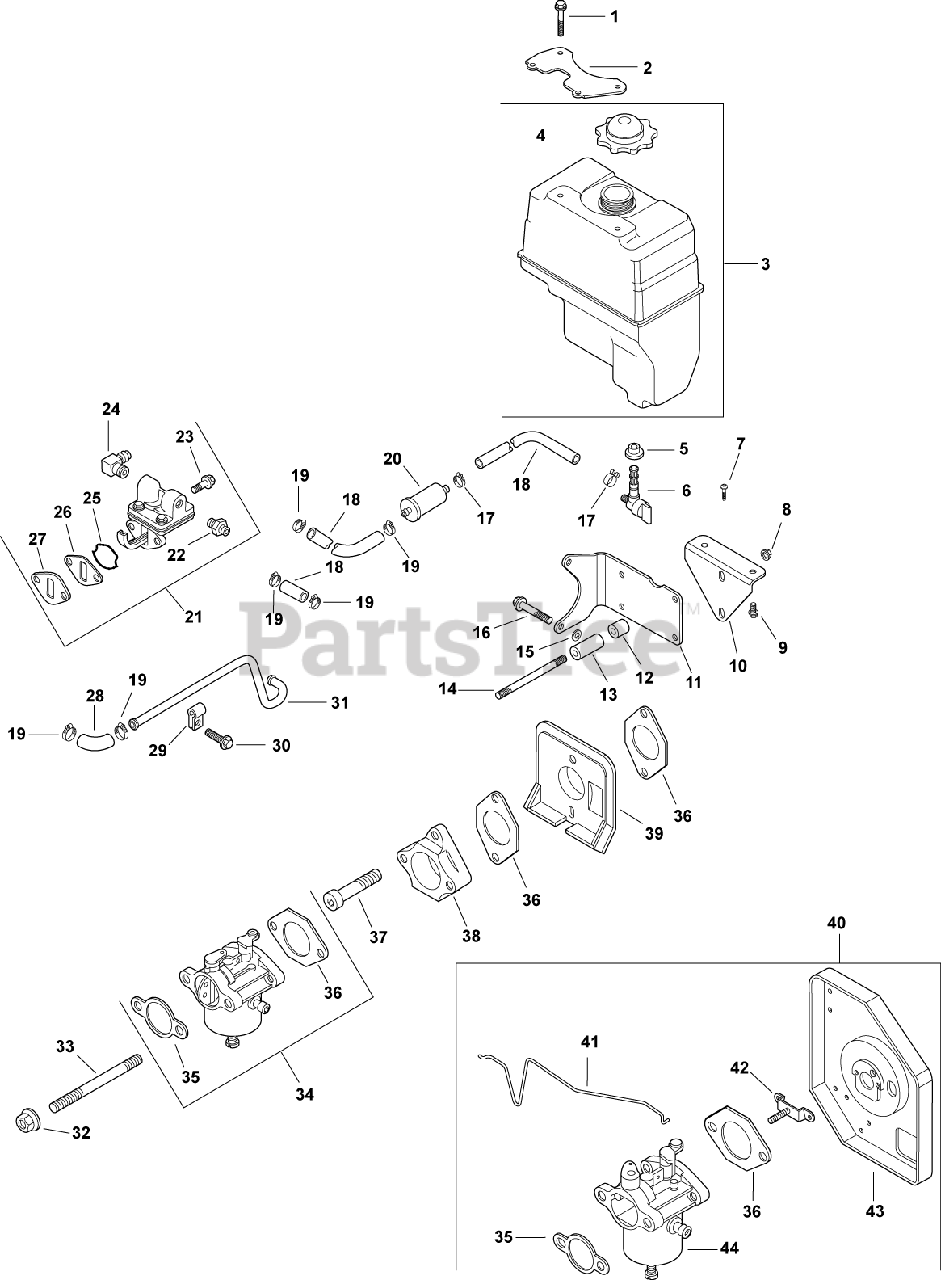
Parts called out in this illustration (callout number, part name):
1	SCREW,FLG THD FRM M6X1.0X25-(#25086395S)
2	BRACKET, FUEL TANK
3	KIT, FUEL TANK
4	CAP, FUEL TANK
5	BUSHING, FUEL TANK
6	VALVE, FUEL SHUT-OFF
7	SCREW, LBD SKT M6x1.0x20-(#25086403S)
8	NUT, FLG M8X1.25
9	SCREW, FLG M6X1.0X12
11	BRACKET, FUEL TANK
13	SPACER, FUEL TANK
14	STUD, M8X1.25X133-USE 25 755 54-S
15	WASHER, FLAT 11/32"
16	SCREW, FLG M8X1.25X50
17	CLAMP, BAND SPRING HOSE-(#2523737S)
18	HOSE,LW PERM.FUEL 24.00"-USE 25 111 81-S
19	CLAMP, HOSE (KM)-USE 25 237 31-S
20	FILTER,FUEL 51 MICRON (FUEL PUMP)
21	KIT, FUEL PUMP
22	KIT, STRAIGHT FITTING
23	SCREW,FLG THD FRM M6X1.0X20-(#25086396S)
24	CONNECTOR, 90 DEG. HOSE
25	O-RING, FUEL PUMP
26	SPACER, FUEL PUMP
27	GASKET, FUEL PUMP
28	HOSE, FUEL LOW-PERMEATION
29	CLIP, TUBE & WIRING (KM)
30	SCREW, FLG THD FRM M5X.8X10
31	LINE, FUEL - DISCONTINUED
32	NUT, FLG M6X1.0
33	STUD,M6X1.0X116
34	KIT, CARBURETOR w/GASKETS
35	GASKET, AIR CLEANER BASE
36	GASKET, CARBURETOR
37	SCREW, SKT CAP M6X1.0X35
38	ADAPTER, CARBURETOR
39	DEFLECTOR, HEAT
40	KIT, CARB. RETROFIT
41	LINKAGE, CHOKE
42	BRACKET, AIR CLEANER
43	BASE, AIR CLEANER
44	CARBURETOR W/GASEKTS - USE 12 853 139-S
